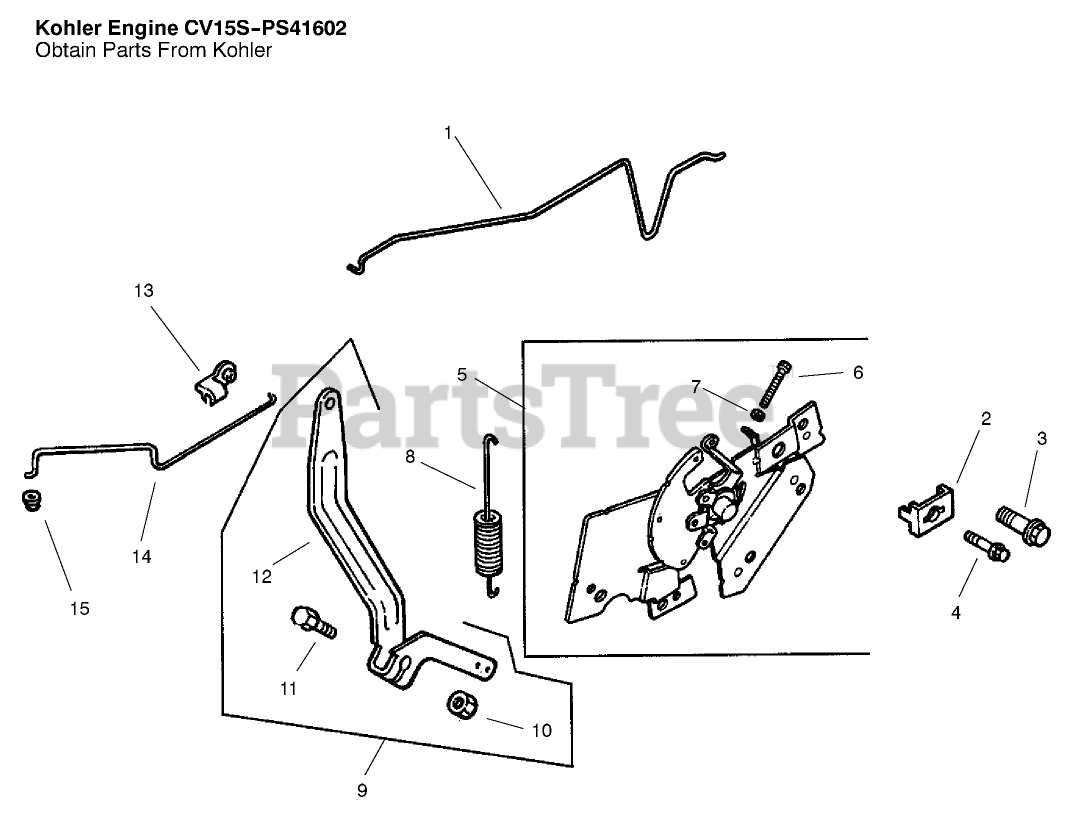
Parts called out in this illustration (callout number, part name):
1	Linkage-Choke (Only On: 72042,72043,72062,72063)
3	Screw-HHF (M5x0.8x16)
4	Screw-Lobe Socket
5	Control-ASM INC 6-7 (Only On: 72042, 72063, 72062, 72043)
6	Screw-HH
7	Nut-Hex
8	Spring-Governor (Only On: 72042, 72063, 72062, 72043)
9	Set-Gasket
12	Lever-Governor
13	Bushing-Linkage
14	Linkage-Throttle (Only On: 72042, 72063, 72062, 72043)
15	Bushing
